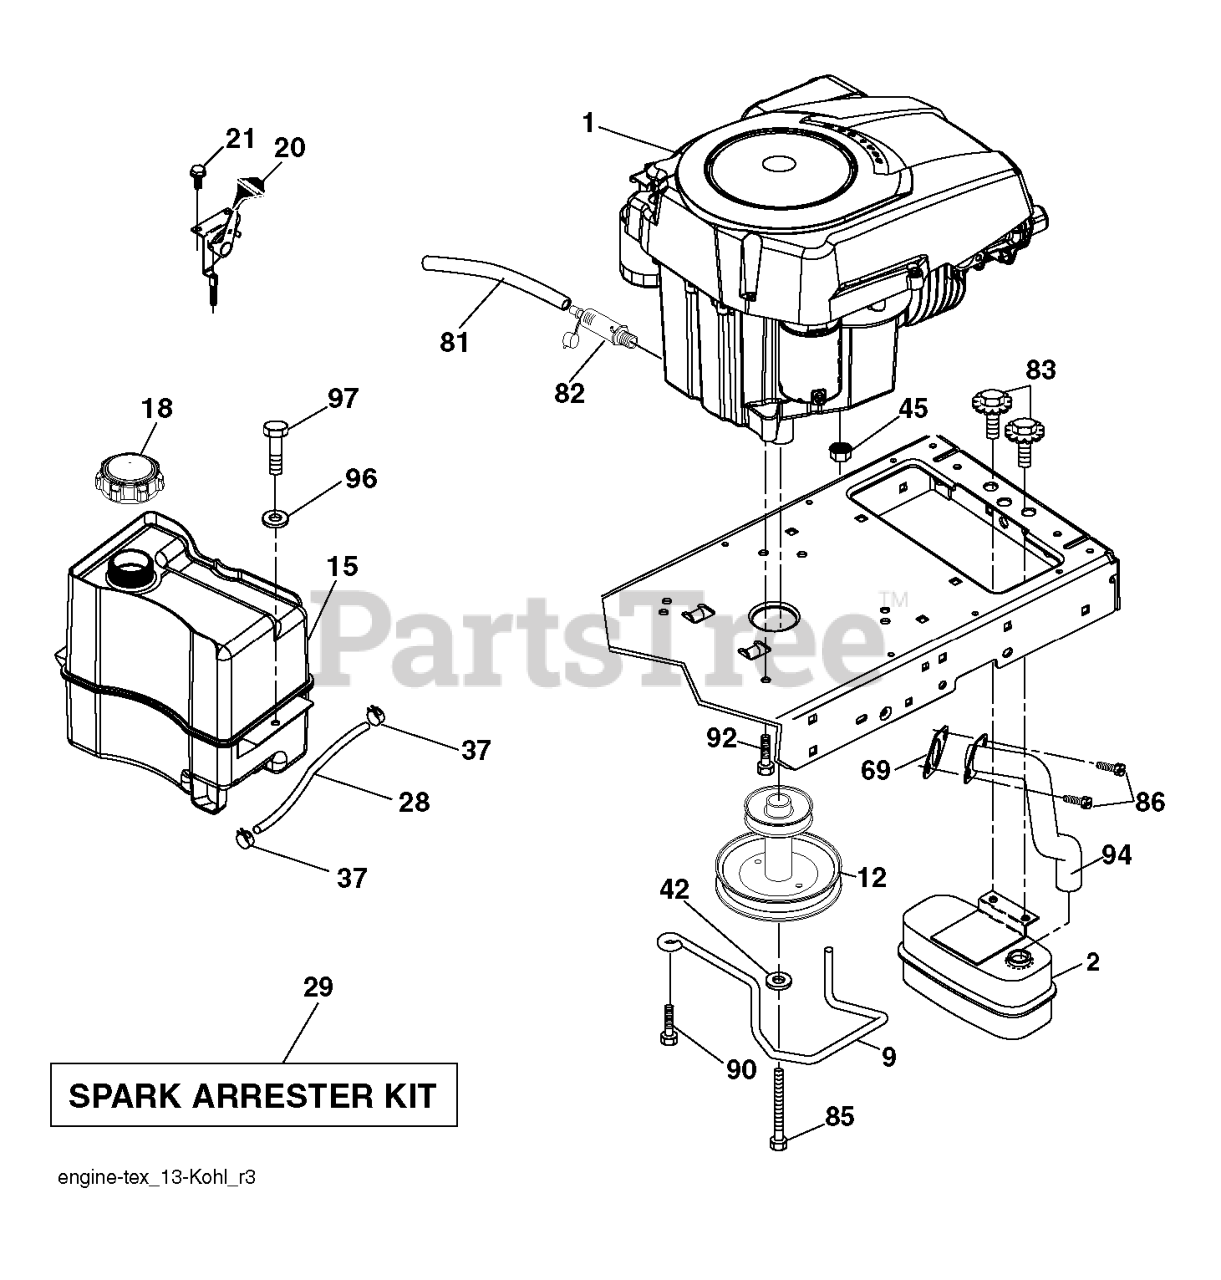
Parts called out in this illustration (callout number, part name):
2	MUFFLER.SINGLE.CYL.KOHL/B&S
9	KEEPER.BELT.ENGINE.3.25 (3 2)
12	PULLEY ENGINE
15	RP TANK FUEL FRT 1.5 GAL
18	FUEL CAP
20	CONTROL.TH/CK.C.
21	SCREW.#10 X 0.750.BOS
28	LINE.FUEL.20
29	KIT.SPARK ARRESTOR 794945 B&S
37	HOSE CLAMP
42	LOCKWASHER
45	NUT
69	GASKET.EXHAUST.KOHLER
81	TUBE, DRAIN OIL ASM.
82	PLUG DRAIN OIL EASY
83	BOLT.5/16-18UNCX3/4 W/SEMS.BLK
85	BOLT HEX 7/16-20X4-1/4"
86	SCREW.SOCKET HD.5/16-1
90	SCREW 3/8-16X1
92	SCREW 3/8-16X1
94	RP.TUBE.EXHAUST.KOHL.COURAGE
97	SCREW HEXWSHR 1/4-20X3/4
